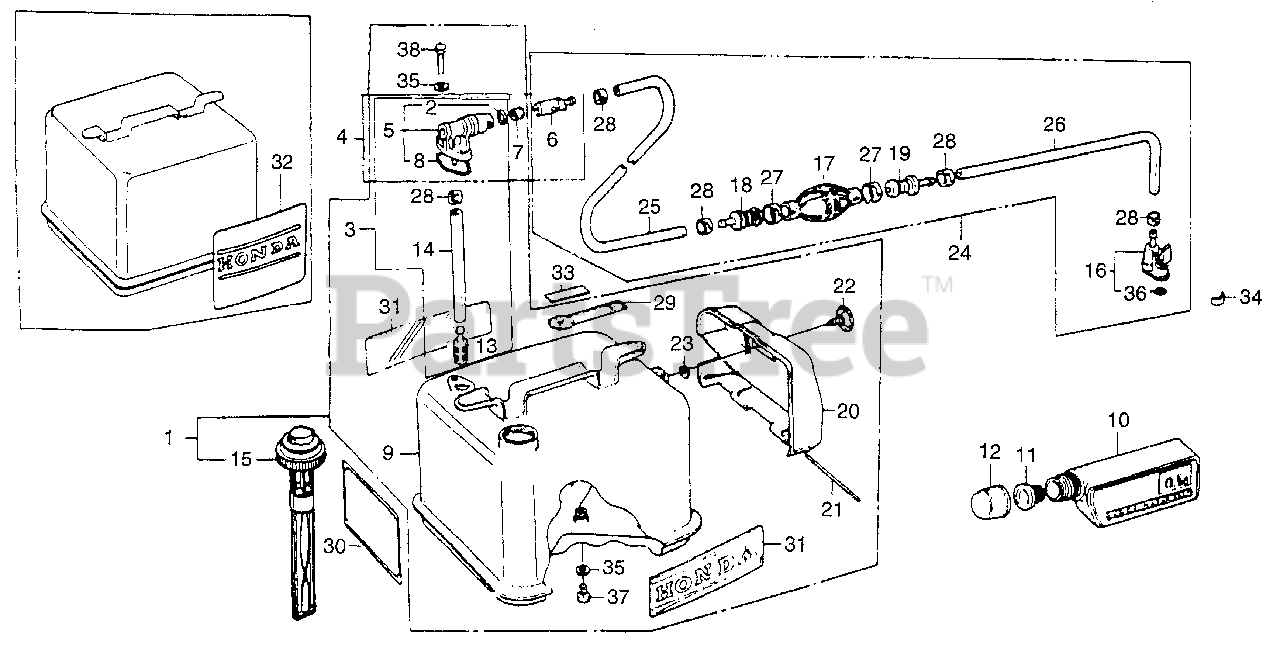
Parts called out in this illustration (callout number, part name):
1	TANK KIT, FUEL *R8* (BRIGHT RED) (NOT AVAILABLE)
3	JOINT A, FUEL
4	JOINT, FUEL CONSENT
5	JOINT A, FUEL CONSENT
6	JOINT B, FUEL CONSENT
7	ABSORBER, FUEL
8	RING, PETCOCK SEAL
9	TANK, FUEL *R8* (BRIGHT RED)
10	TANK, OIL
11	CAP, SUB-TANK (INNER)
12	CAP, SUB-TANK
13	FILTER, FUEL
14	TUBE (INNER)
15	CAP, FUEL FILLER (NOT AVAILABLE)
16	CONNECTOR, FUEL *NH1* (BLACK)
17	BULB, PRIMER
18	VALVE, IN.
19	VALVE, OUTLET
21	BAR (3X150) (NOT AVAILABLE)
22	LATCH, TOOL BOX
23	STOPPER, LATCH
24	TUBE, FUEL *B9* (ATLANTIS BLUE) (NOT AVAILABLE)
25	TUBE, FUEL LONG
26	TUBE, FUEL SHORT
27	BAND, TUBE CLIP (20MM)
28	BAND, TUBE CLIP (11MM)
29	MARK, TANK CAUTION (ENGLISH/FRENCH)
32	MARK, TANK (ENGLISH)
35	GASKET, FIBER (6MM)
36	O-RING (5.5X3)
37	BOLT, HEX. (6X12)
38	BOLT, HEX. (6X16)
